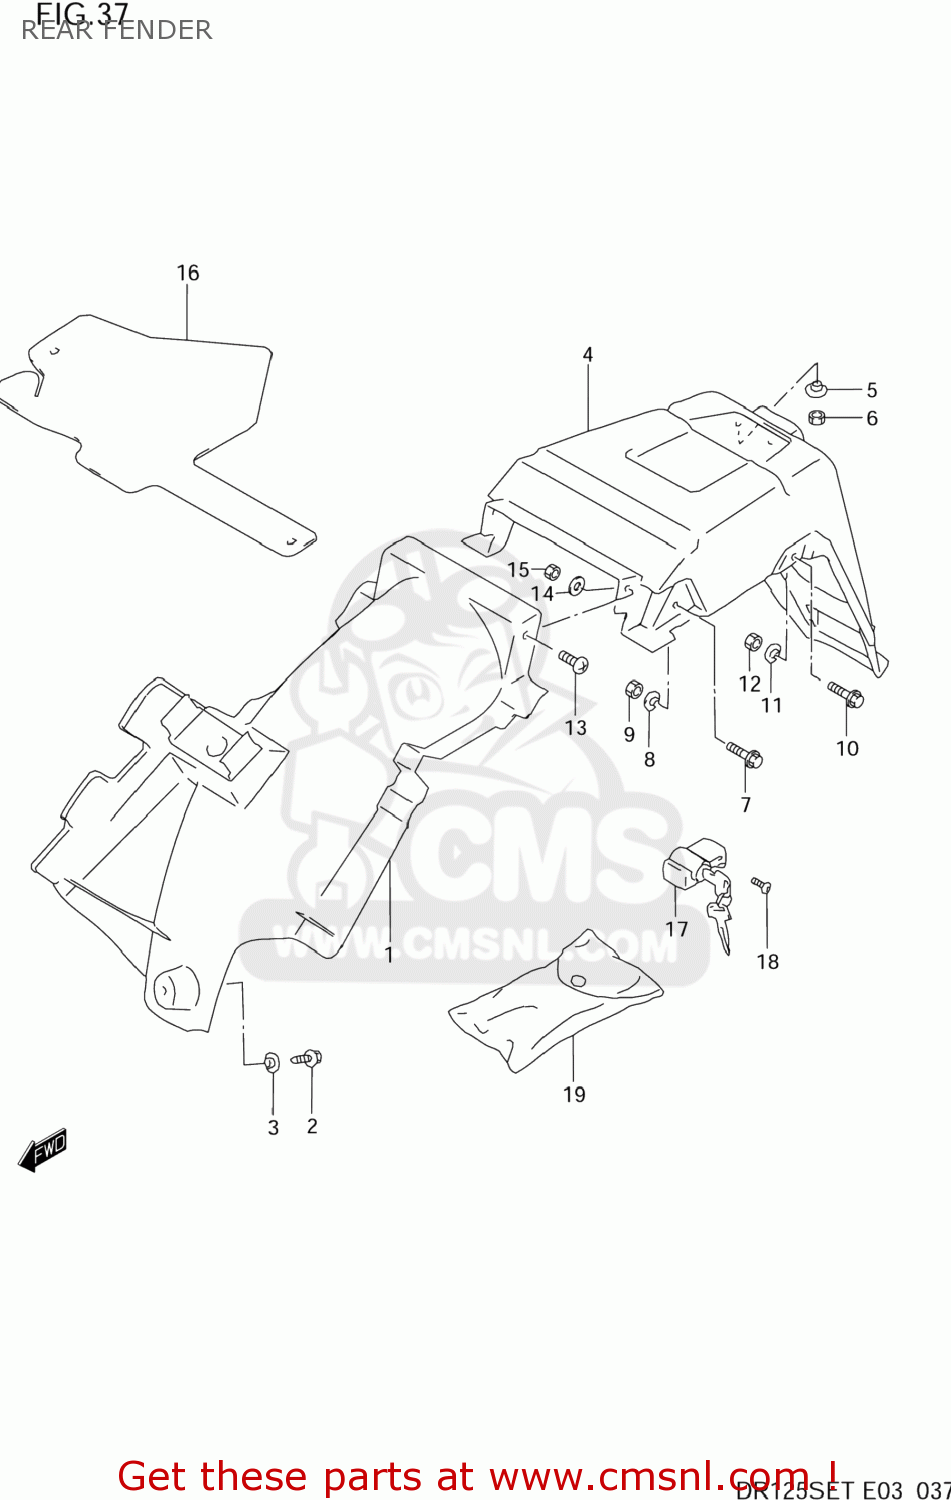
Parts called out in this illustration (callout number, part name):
1	BODY COMP,REAR FENDER
2	BOLT
3	WASHER
4	BODY ASSY,RR FENDER RR
5	WASHER
6	NUT
7	BOLT
8	WASHER
9	NUT
10	BOLT
11	WASHER
12	NUT
13	SCREW
14	WASHER
15	NUT
16	MUDFLAP,RR FENDER FR
17	LOCK SET,HELMET
18	SCREW(6X14)
19	TOOL ASSY
